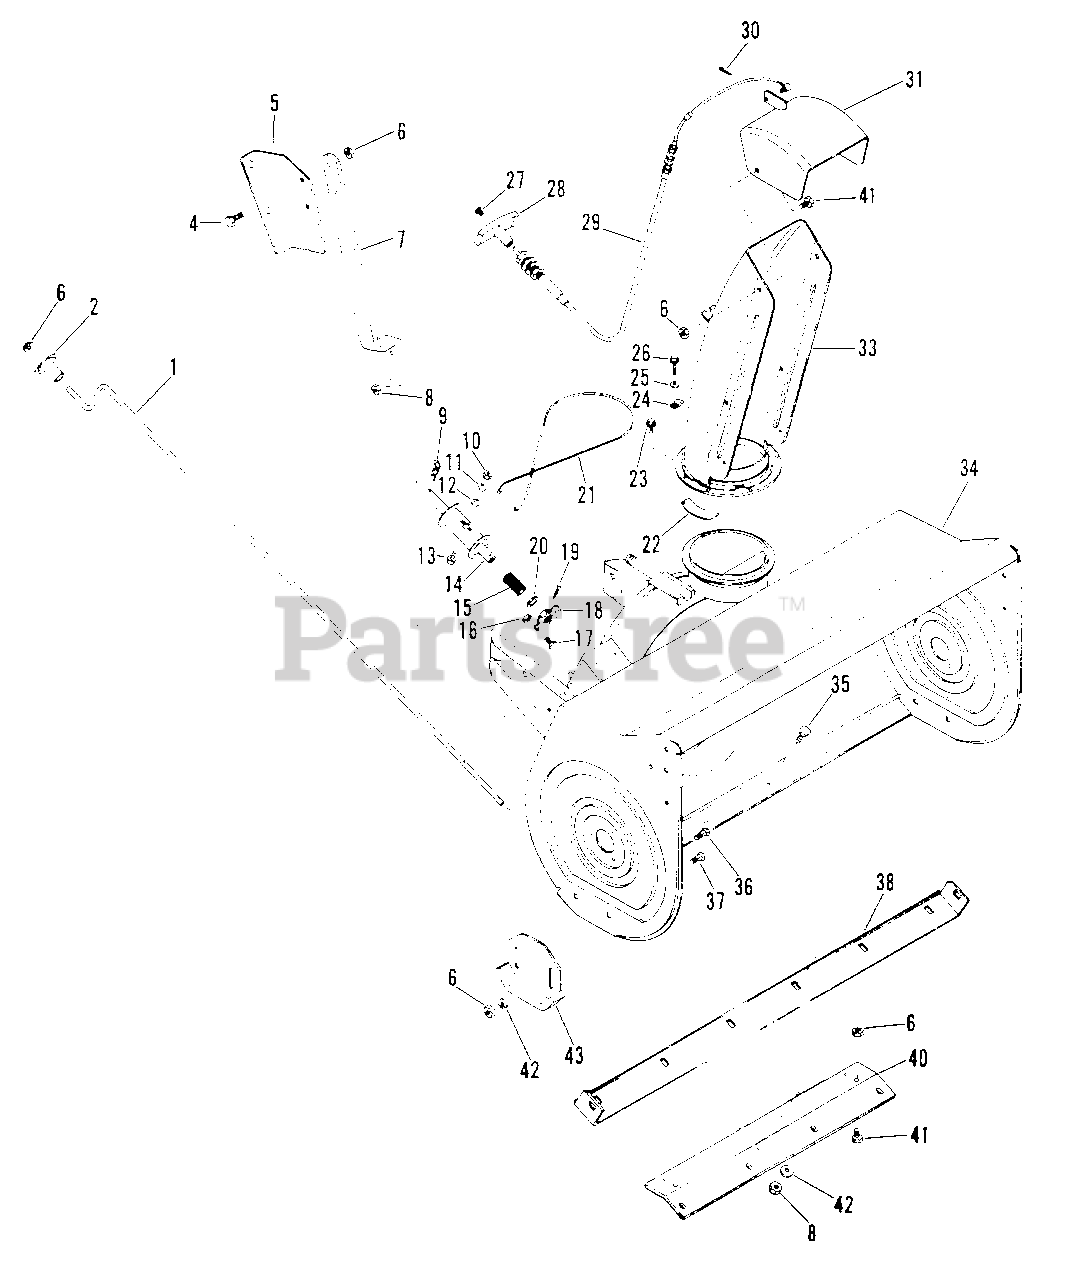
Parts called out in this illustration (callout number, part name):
1	Crank, Chute Control
2	Knob
4	Bolt, Hex 3/8-16x1.00
5	Bracket, Control
6	Nut, Lock 3/8-16
7	Support, Chute Crank
8	Nut, Lock 5/16-18
9	Hairpin, Internal
10	Nut, Hex 1/4-20
11	Washer, Lock 5/16 Reg.
12	Washer, Flat .281x.625x.065
13	Bolt, 1/4-20x.625 Rd Hd Sq Nk
14	Spool
15	Spring, Comp. 1.6 Free Length
16	Nut, Lock #10-24 Twin Whiz
17	Screw, #10-24x.375 Cap
18	Assembly, Disc.
19	Pin, Spring .187x1.00
20	Washer, Flat .640x1.005x.06
21	Cable
22	Clamp, Chute
23	Screw, Tapping 10-24x.50 HHD
24	Clamp, Cable
25	Washer, Flat .188x.375x.049
26	Taptite, #10-24x.75 PHD
27	Screw, Mach. 8-32x.75 PHD
28	Knob, Black
29	Cable, Control
30	Pin, Cotter .09x.75
31	Deflector, Chute
33	Chute, Discharge
34	Housing, 36" Snowblower
35	Bolt, Carriage 5/16-18x.75
36	Bolt, 3/8-16x1.00 Rd Hd Sq Nk
37	Bolt, 3/8-16x.75 Rd Hd Sq Nk
38	Blade, Scraper
40	Brace, Blade
41	Bolt, Hex 3/8-16x.75
42	Washer, Flat .406x.812x.065
43	Skid
